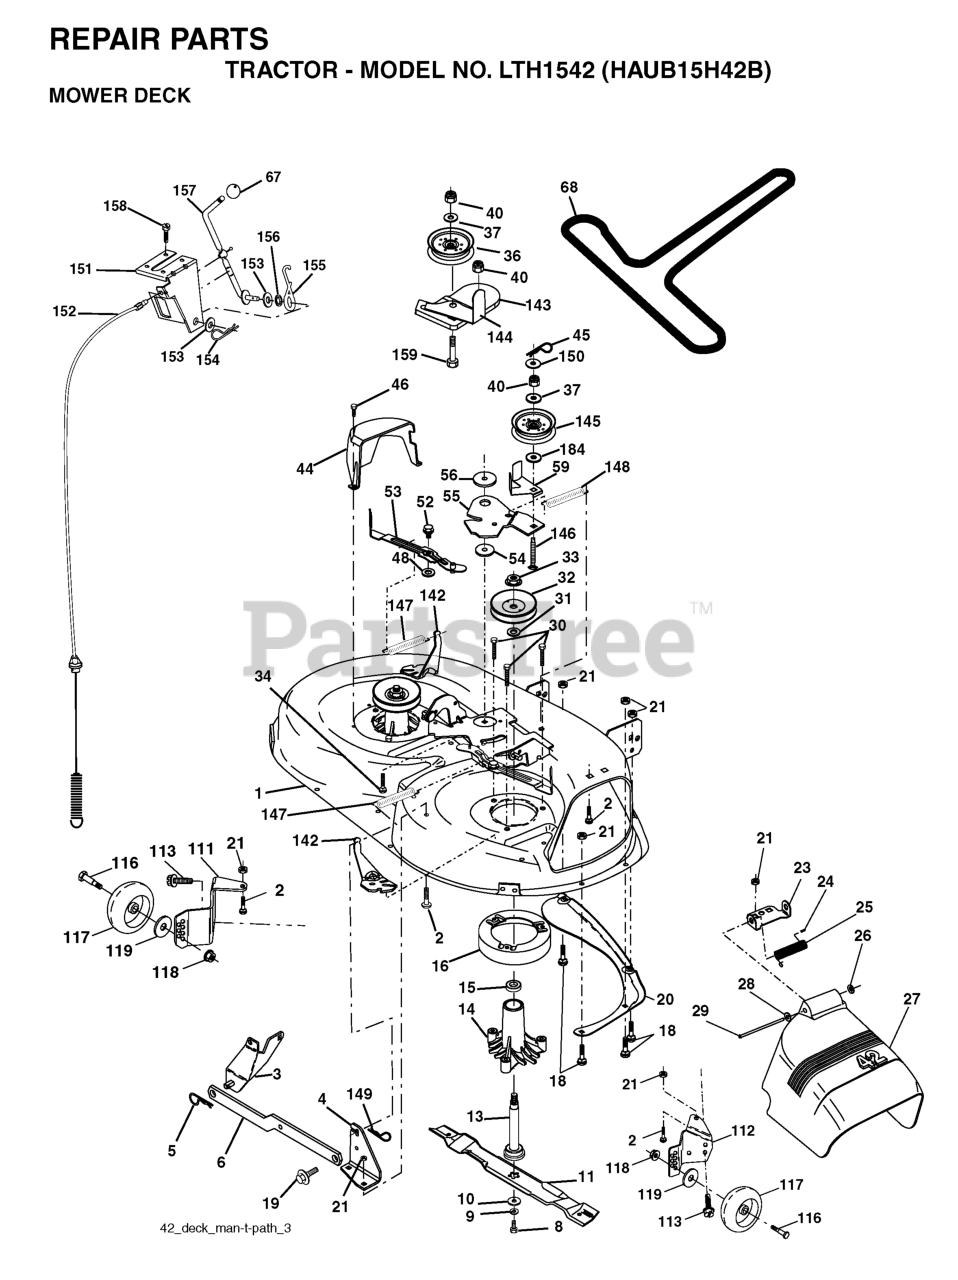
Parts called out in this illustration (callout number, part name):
1	DECK SVC 42"
2	RP BOLT 5/16-18 X3/4 ZN/YEL GR
3	BRKT ASM SWAY BAR
4	BRACKET SWAY BAR 42" DECK
5	RETAINER-SPRNG RB
6	BAR SWAY DECK
8	BLADE BOLT
9	LOCKWASHER
10	WASHER.BLADE
13	SHAFT ASM VENT
14	HOUSING.MANDREL.VENTED (MACHD)
16	STRIPPER.MANDREL.ROUND.BLACK
18	BOLT
19	BOLT SHD 5/16-18
20	BAFFLE.VORTEX
21	LOCKNUT
23	BRKT, DEFL. MOWER
24	CAP-SLEEVE LT
25	SPRING TORSION
26	NUT PUSH M
27	SHIELD DEFLECTOR
28	Washer 11/32 x 5/8 x 16 Ga SD
29	ROD.HINGE
30	SCREW, WASHER HEAD
31	WASHER
32	PULLEY MANDREL
33	NUT, FLG TOPLOCK 9/16"
36	PULLEY.IDLER.FLAT
37	WASHER
44	GUARD MANDREL LH BLACK
45	RETAINER M
46	SCREW.1/4-20X5/8
52	BOLT.SHOULDER.5/16-18
53	ARM BRAKE ASSY
55	ARM IDLER 42" MOWER LT/YT
56	SPACER RETAINER
59	GUARD TUV IDLER
67	KNOB T (3/8 HOLE)
68	BELT V SECONDARY
111	GUAGE WHEEL BRACKET LH
112	BRACKET WHEEL GUAGE KIT
113	Screw Tapping 3/8-16 x .625
116	BOLT M
117	WHEEL.GAUGE.STANDARD
118	LOCKNUT
119	WASHER.5/16.FLAT.STE.STD.
142	ARM SPRING BRAKE MOWER
143	BRACKET, ARM IDLER
144	KEEPER BELT 42" CLUTCH
145	PULLEY.IDLER.FLAT.PLATED
146	BOLT CARRIAGE IDLER
147	SPRING EXTENSION
148	IDLER RETURN SPRING
149	SPRING.RETAINER.YELLOW.ZINC
151	BRACKET.CLUTCH.CABLE
152	CLUTCH CABLE 42"
153	WASHER FLAT 3/8"
154	SPRING RETAINER
155	SPRING RETENTION LEVER
156	SPACER.CLUTCH.CABLE
157	ROD CLUTCH CABLE 3/8"
158	SCREW
184	WASHER
